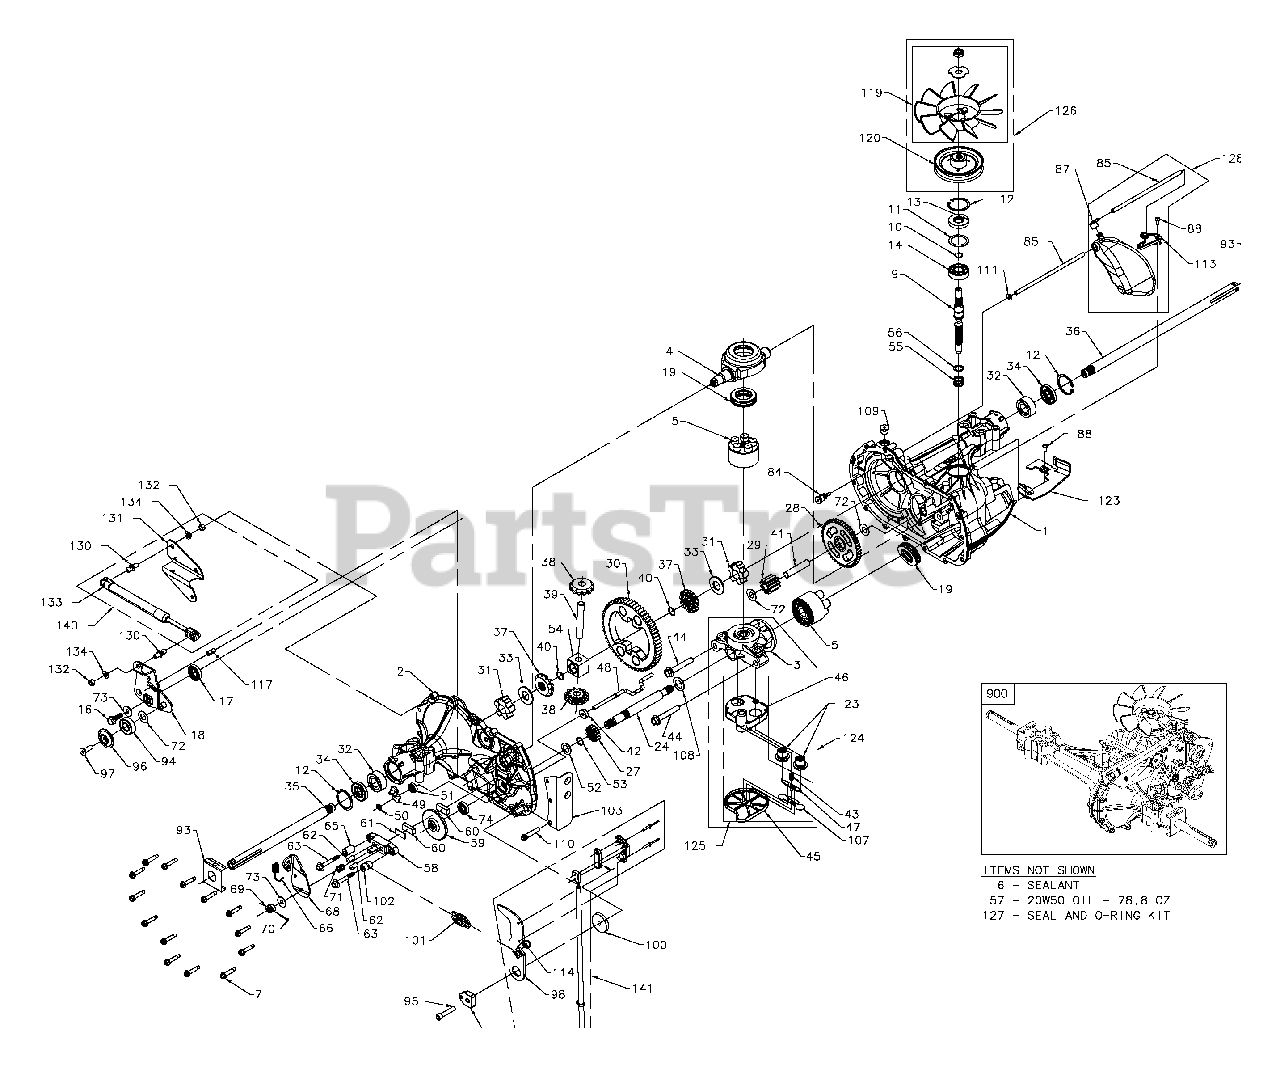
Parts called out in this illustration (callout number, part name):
1	Kit, main housing Main housing, machined
2	Kit, side housing
2	Side housing, machined
3	Kit, center section Center section, machined
4	Swashplate, trunnion machined
5	Kit, cylinder block
5	Block - cylinder Piston, Spring, compression
5	Washer thrust
6	Sealant tube
7	Hex flange screw 1/4-20 x 1.25
9	Shaft, input
10	Retaining ring
11	Spacer
12	Retaining ring
13	Seal, lip .67 X 1.58 X .276
14	Bearing, ball 6203 (BDR)
16	Hex flange head screw 1/4-20 x 1.25
17	Seal, lip 18 x 32 x 7
18	Arm, control
19	Bearing, thrust (10cc)
23	Check plug assembly, .027 Washer
24	Shaft motor
27	Gear, pinion, 13T
28	Gear 1 OT / 48T
29	Gear, 1 OT jackshaft
30	60T bullgear
31	Sleeve bearing .75 X 1.75 X.625
32	Sleeve bearing (outboard) .75 X 1.575 X.
33	Washer
34	Lip seal, axle shaft
35	Shaft, axle (keyed, R.H.)
36	Shaft, axle (keyed, L.H.)
37	Miter gear (splined)
38	Miter gear
39	Differential shaft (310-0750)
40	Retaining ring
41	Pin, jackshaft
42	Magnet, ring
43	Spring, bypass
44	Bolt 3/8-24 x 2-1/2
46	Base, filter
47	Actuator, bypass
48	Rod, bypass actuator
49	Arm, bypass
50	Retaining ring.25 External
51	Seal, lip .741 X .25 X .25
52	Washer, flat 0.050" (210-1000)
53	Retaining ring
54	Bearing, center block
55	Spring, helical compression
56	Washer, block thrust
57	Oil
58	Kit, brake yoke
59	Rotor, brake
60	Brake puck
61	Brake puck plate
62	Pin, brake actuating
63	Hfhcs 1/4-20 x 2 w/patch, special flange
65	Spacer, brake torsion spring
66	Spring, brake arm bias
68	Arm-brake, RH
69	Nut, castle 5/16-24
70	Pin, cotter 3/32x3/4
71	Brake spring
72	Washer (310-0750)
73	Washer, flat
74	Seal, oil
84	Fitting, 5/16 x sae 5/32 tube
85	Hose, expansion tank
87	Cap, barbed vent
88	Bolt, self tapping (BDR)
93	Spring clip, housing
94	Bearing, ball
95	Screw, 5/16-24x 1 1/2 socket head cap
96	Spacer, locating
97	Screw
98	Arm, return
99	Puck, adjusting
100	Washer,.325 Odxl.6 Idx.15 TK
101	Spring, extension
102	Spacer, .56 Odx.26 ID x.87
103	Bracket, torque
107	Deflector
108	Washer, motor shaft.71 ID x 1.150D x.03 Thick
109	Plug, straight thread 9/16-18
110	Screw, torx head 5/16-18
111	O-ring .7 X .301 ID
113	Bracket, support expansion tank
114	Spring guide
117	Pin, spring 5/16 x.75
119	Kit, fan - washer - nut, Fan, 7 in
119	Hex lock nut 1/2-20 (nylon insert)Washer,
120	Pulley
123	Belt keeper
124	Center section filter bypass assembly Center section
124	Base filter w/ poppet check plug assembly,
124	.027 Washer Spring, bypass actuator,
125	Kit, filter Bottom, filter spring,
125	bypass actuator,
125	bypass deflector
125	Base, filter w/ poppet
126	Kit, fan/pulley, Hex jam 1/20-20 (nylon insert) washer,
126	OD slotted, .53 X 1.63 X.06 Fan, 7 in,
126	Pulley
127	Kit, seal
127	O-ring .07 X .301 ID
128	Kit, expansion tank,
128	Tank,
128	expansion assembly cap,
128	barbed vent.,
128	Bolt, self tapping 10-32 x 1/2 bracket,
128	support expansion tank hose, expansion tank
130	Stud, threaded ball
131	Bracket, cruise/damper
132	Nut 5/16-18
133	Damper
134	Washer, 5/16 lock
140	Kit, damper, Stud, threaded ball bracket,
140	cruise/damper hex nut 5/16-18 NC damper,
140	Washer, helical spring lock 5/16, regular
141	Kit, RCS, Arm, return spring guide switch,
141	RCS activator,
141	RCS switch spring,
141	RCS switch retainer,
900	Transaxle
